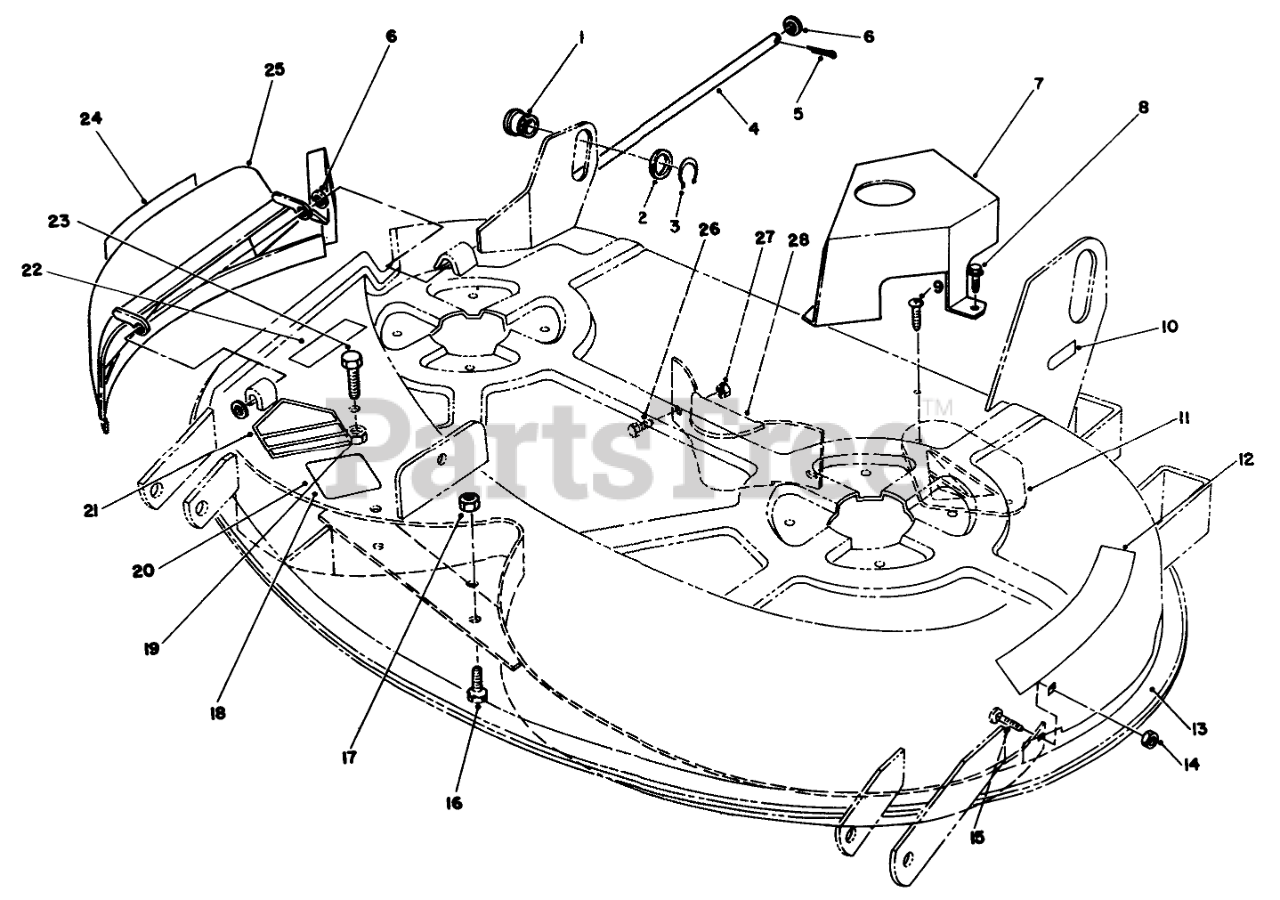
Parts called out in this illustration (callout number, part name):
1	ROLLER-LIFT
2	Washer
3	Snap Ring
5	PIN-COTTER
6	WASHER 5/16 SAE
7	Cover-Belt
8	SCREW-HWHTF
9	#8 X .625" PHILPS PAN H
10	Decal-Attach-A-Matic
11	PLATE-KICKER
12	DECAL-DANGER
13	DECAL-38" RECYCLER
14	NUT-LOCK, NI
15	BOLT-CARR
16	Bolt
17	NUT-LOCK, NI
18	Baffle-38"
19	NUT-LOCK, NI
20	Decal-Routing
21	DECAL-DANGER
22	DECAL-DANGER
23	SCREW-HH
24	DECAL-DANGER, THROWN OBJECT
25	Chute-Recycler
26	SCREW-HH
27	NUT-LOCK, NI
28	Baffle-Rear
